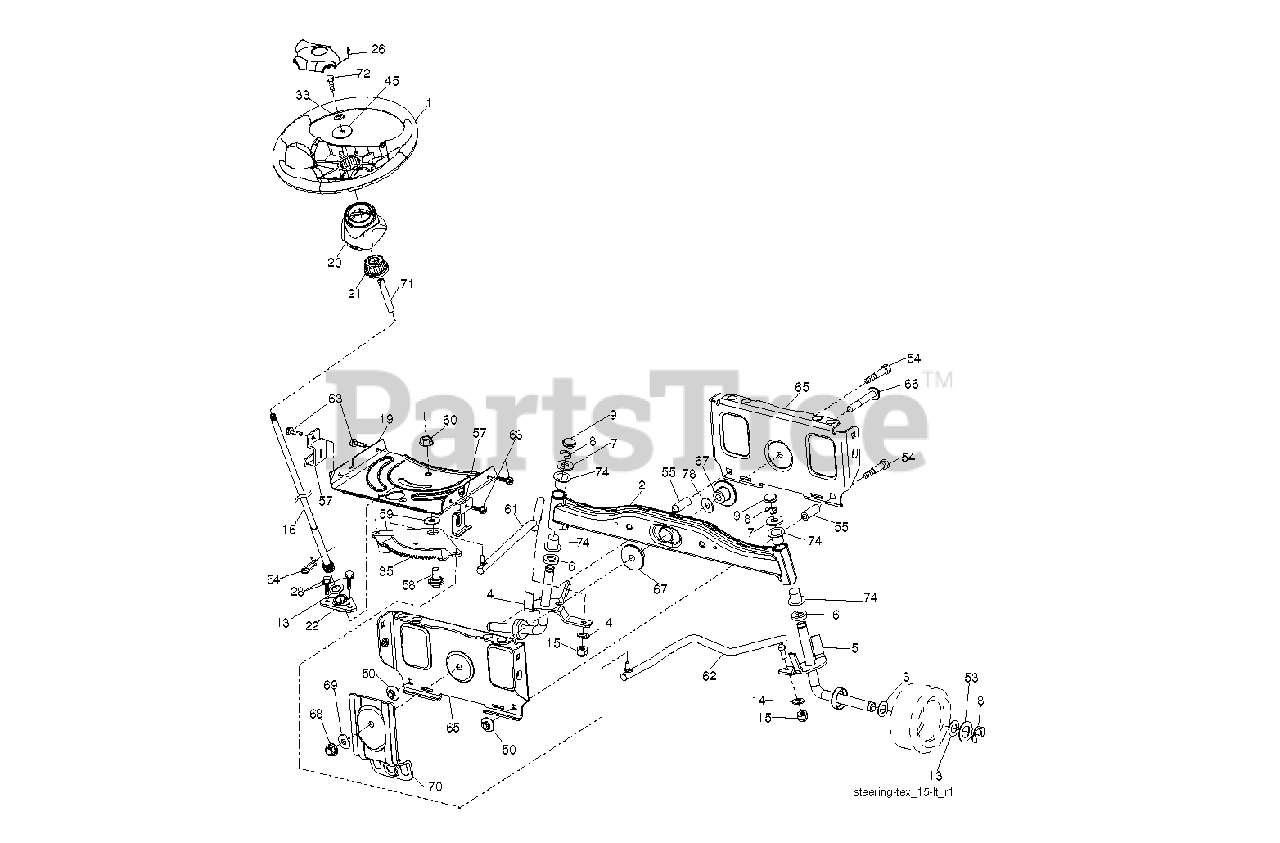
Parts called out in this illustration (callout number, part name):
2	AXLE.HALF.ASM.WELDED
4	SPINDLE.WELDED.LH.15"TEX
5	SPINDLE.WELDED.RH.15"T
8	RING CLIP
9	CAP.SPINDLE
14	WASHER, LOCK 3/8
15	NUT CROWNLOCK 3/8-24
16	SHAFT STEERING
19	PLATE.STEER.DDL.NLT/NG
20	BOOT STEERING BLACK
21	ADAPTER, WHEEL STNG..
22	BUSHING.ASM.STEERING.A
26	INSERT.CAP.STRG.WH.BLACK
28	SCREW, 3/8-16X3/4
33	LOCKWASHER
35	GEAR.SECTOR.PLATE.DDL.
45	WASHER.11/32
50	NUT LOCK FLG 3/8-16 UNC
53	WASHER.HARDENED
55	SPACER.BRACE.AXLE
57	BRACKET.UPSTOP.TEX
58	BOLT.SHOULDER.SECTOR.P
59	WASHER.THURST.SECTOR.S
60	NUT FLANGE LOCK 5/8-11
61	DRAGLINK.LH.BALLSTUD.D
62	DRAGLINK.RH.BALLSTUD.D
63	SCREW
64	RETAINER.CLIP.SPRING.S
65	BRACE.AXLE.FRONT.NLT/N
66	BOLT HEX FGHD 7/16-14 X 3 SERR
67	BUSHING.PM.FRONT AXLE
68	NUT.LOCK.FLANGE.7/16
69	WASHER.1.5X.505X.118
70	BRKT.DECK.SUSPENSION.F
71	SHAFT EXTENSION STEERING
72	BOLT YT
74	BRNG T
78	THRUST WASHER
